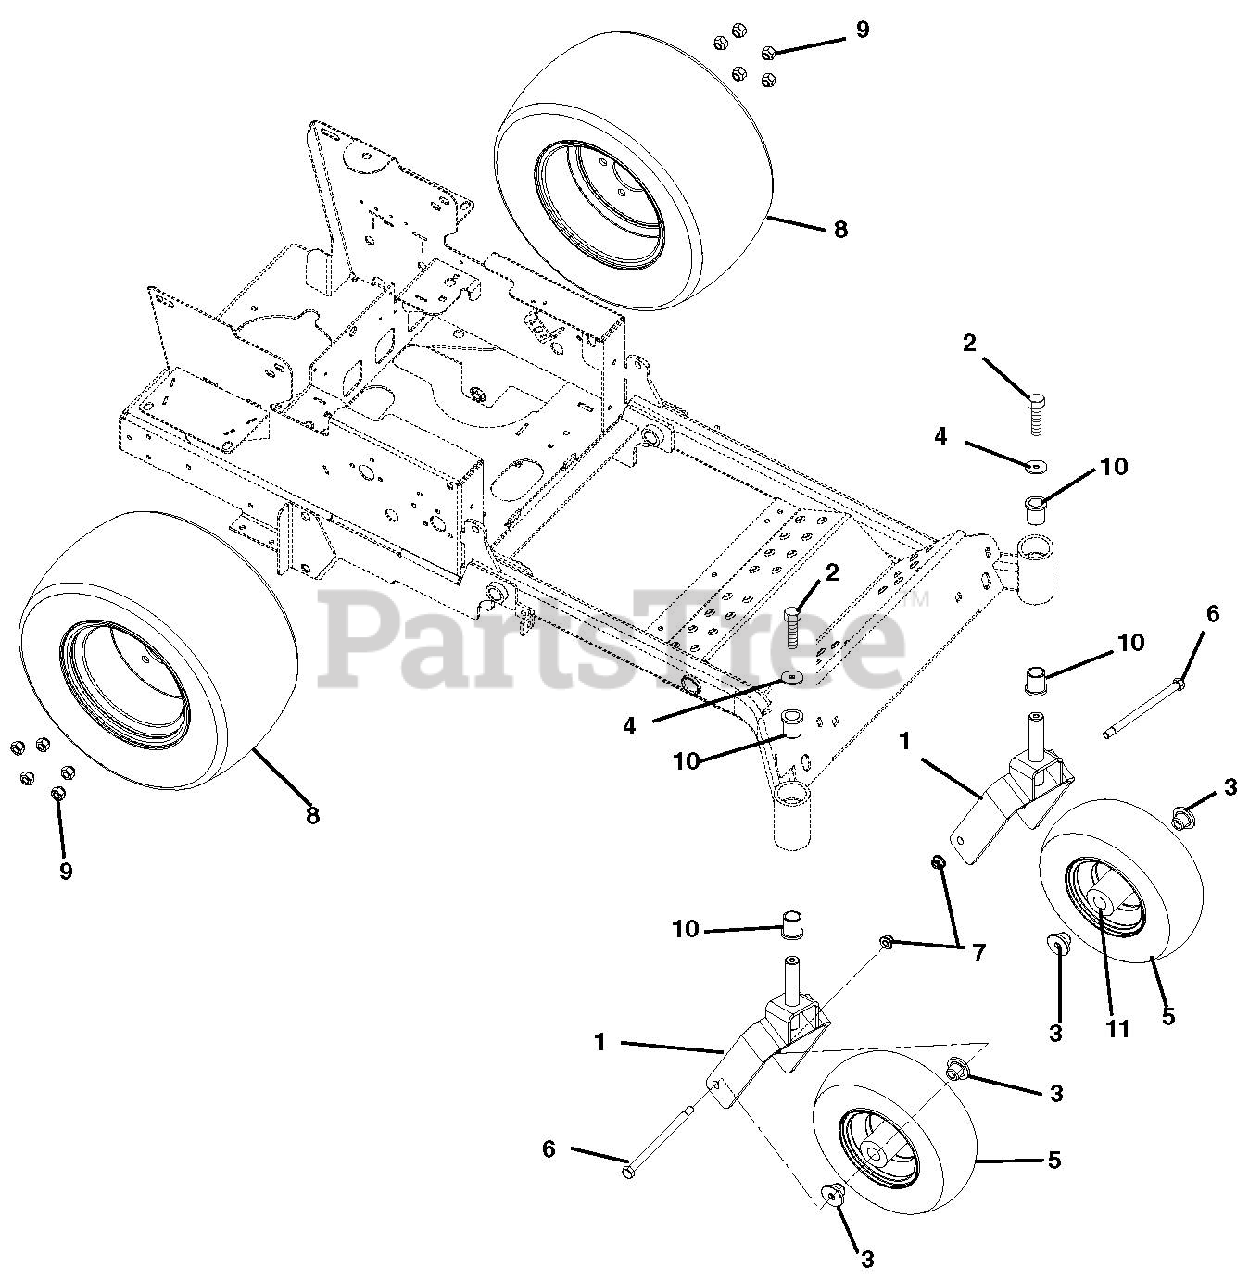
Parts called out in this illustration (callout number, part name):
1	Weldment, Front Fork
2	Bolt, Hex .38-16 x 1.00
3	Spacer, Wheel
4	Washer, Flat-Steel .380 x 1.50 x .125
5	Tire/Wheel Assembly, 13 x 5.00-6
5	Tire, 13 x 5.00-6
6	Bolt, Hex .50-13 x 7.50 Grade 5
7	Nut, Nyloc Flange .50-13
8	Tire/Wheel Assembly, 20 x 10.00-10
8	Tire, 20 x 10.00-10
9	Wheel Nut .50-20
10	Bushing, Flange 1.00 x 1.25 x 1.50 x 1.50
11	Bearing, 25MM ID x 52MM OD x 15MM
